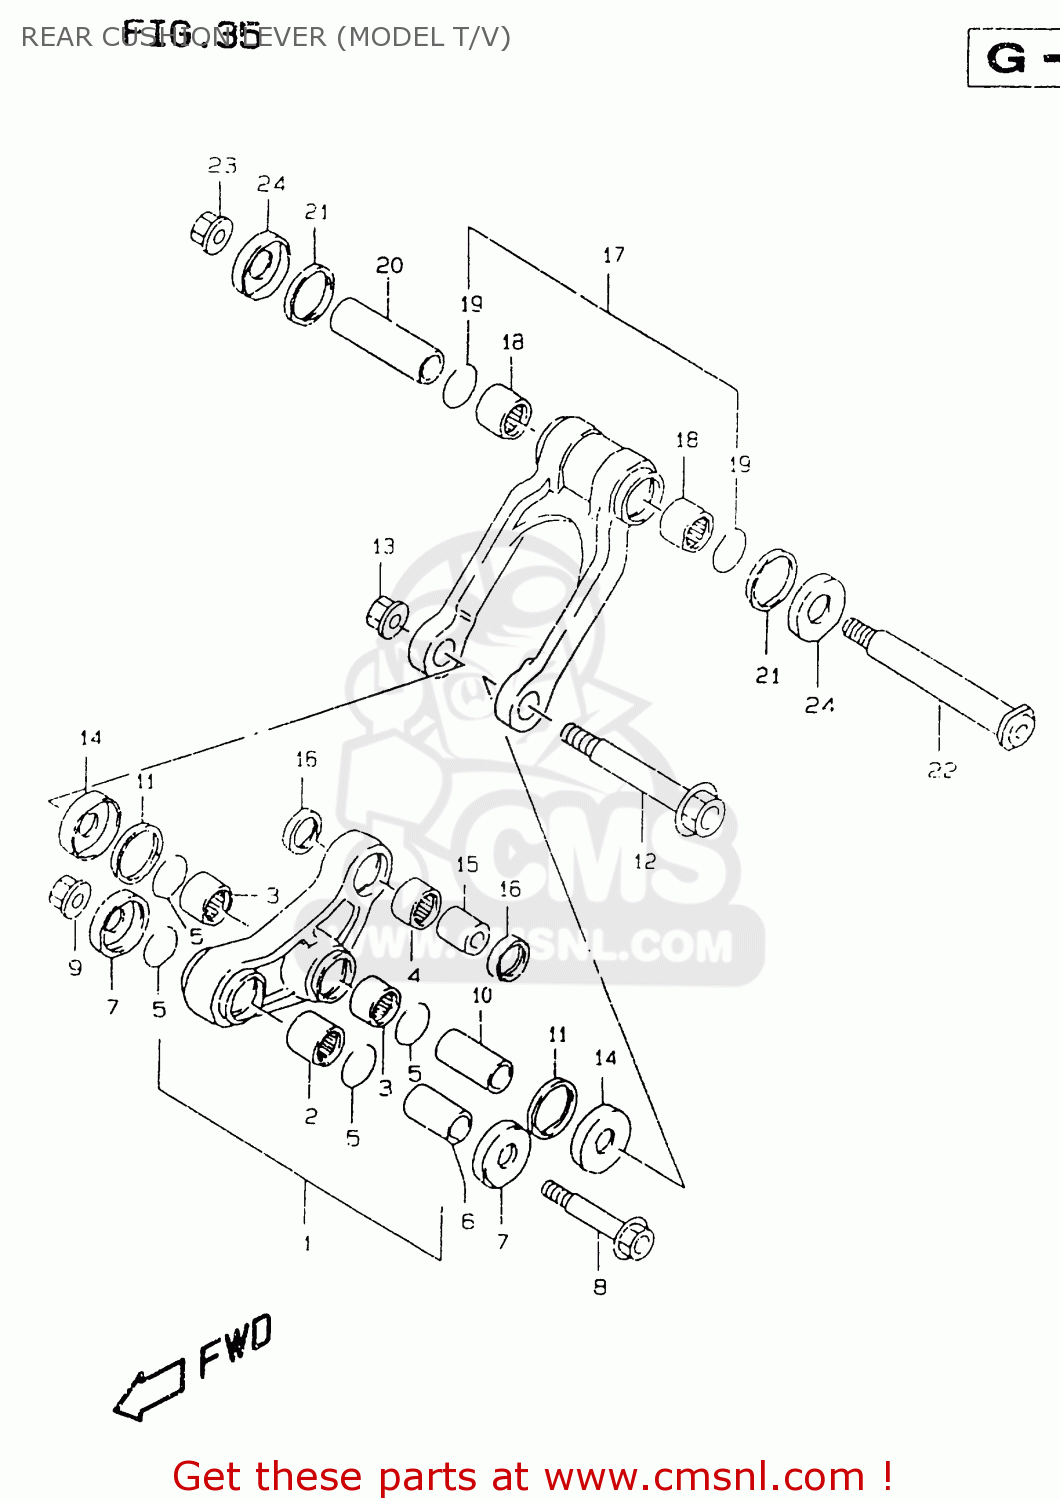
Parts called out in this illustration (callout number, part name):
1	LEVER SET,RR CUSHION
2	BEARING(20X27X25)
3	BEARING(22X28X20)
4	BEARING(20X26X12)
5	CIRCLIP
6	SPACER,RR CUSHION LEVER FR
7	SEAL,RR CUSHION LEVER FR DUST
8	BOLT,RR CUSHION LEVER FR
9	NUT 12MM
10	SPACER,RR CUSHION LEVER CTR
11	SEAL,RR CUSHION LEVER CTR
12	BOLT,RR CUSHION LEVER CTR
13	NUT
14	CAP,RR CUSHION LEVER CTR
15	SPACER,RR CUSHION LEVER RR
16	SEAL,OIL(20X26X4.5)
17	LEVER SET,REAR CUSHION
18	BEARING(22X28X20)
19	CIRCLIP
20	SPACER,RR CUSHION ROD
21	SEAL,RR CUSHION LEVER CTR
22	BOLT,RR CUSHION ROD
23	NUT
24	CAP,RR CUSHION LEVER CTR
